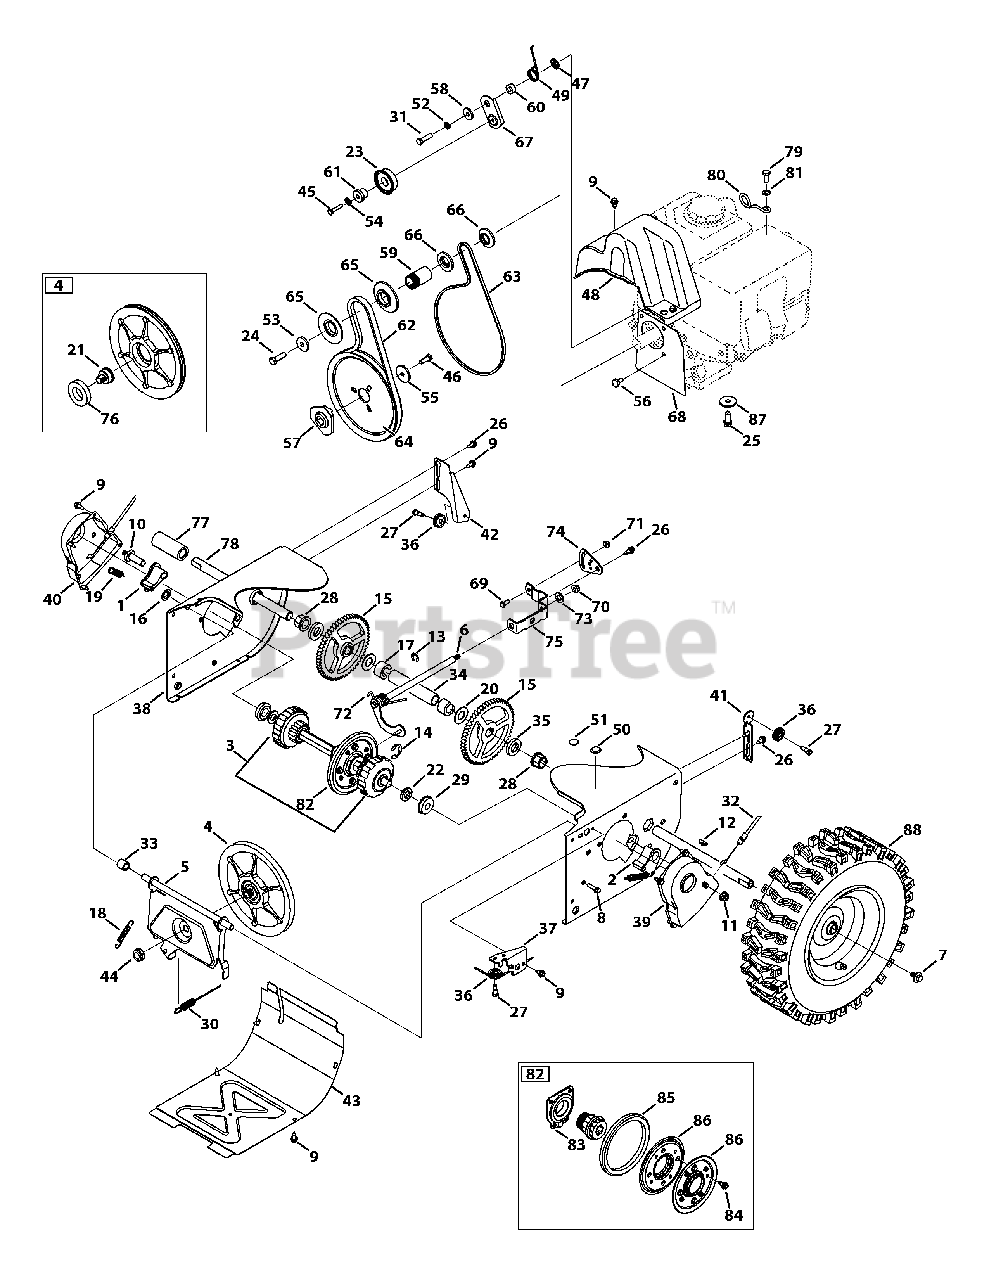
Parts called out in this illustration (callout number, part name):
1	Dogg Assembly, RH
2	Dogg Assembly, LH
3	Drive Shaft Assembly (w/.8125 diam hex shaft)
3	Drive Shaft Assembly (w/.75 diam hex shaft)
4	Friction Wheel Disc Assembly
5	Friction Wheel Support
6	Rod Shift Assembly
7	Screw, 5/16-24 x .750
8	Screw, 1/4-20 x 1.000
9	Screw, 1/4-20 x .625
10	Actuator Shaft
11	Nut, Flangelock, 3/8-16
12	Hi-Pro Key, 3/16 x 3/4 DIA
13	E-Ring
14	Retainer Ring
15	Gear, 56T
16	Nut, Speed, .500
17	Spacer, .76 x .75
18	Extension Spring, .380 x 2.500
19	Extension Spring, .500 x 1.71
20	Washer, Flat, .76 x 1.49
21	Friction Pin, Disc Bearing
22	Spacer .68 ID x 1.25 OD x .20
23	Pulley Assembly
24	Hex Head Screw, 3/8-24 x 1.25
25	Taptite Sems Screw, 3/8-16 x 1.000
26	Screw, Shoulder, .368 x .113 x 1/4-20
27	C Screw, Shoulder, .340 x .335 x 1/4-28
28	Hex Flange Bearing, .75 ID
29	Ball Bearing 17 x 40 x 12
29	Ball Bearing .5625 x 1.375 x .4375
30	Drive Clutch Cable
31	Hex Head Screw, 5/16-24 x 1.25
32	Steering Cable
33	Spacer, .508 x .75
34	Axle Support Tube
35	Spacer, Axle
36	Roller Cable
37	Auger Cable Guide Bracket
38	Wheel Drive Frame
39	Shaft Retainer, LH (w/.8125 diam hex shaft)
39	Shaft Retainer, LH( w/.75 diam hex shaft)
40	Shaft Retainer, RH (w/.8125 diam hex shaft)
40	Shaft Retainer, RH( w/.75 diam hex shaft)
41	Auger Clutch Cable Guide Bracket
42	Drive Clutch Cable Guide Bracket
43	Frame Cover
44	Nut, Flange, 5/8-18
45	Taptite Screw, 1/4-20 x 1.250
46	Hex Head Screw, 5/16-24 x .875
47	Nut, Push-On, .25 DIA
48	Belt Cover
49	Spring, Torsion, .850 x .333
50	Plug, 3/8 ID
51	Plug, 1/2 ID
52	Washer, Lock, 5/16
53	Washer, Flat, .45 x 1.5
54	Washer, Lock, 1/4
55	Washer, Flat, .34 x 1.50
56	Screw, Shoulder
57	Pulley Adapter, .75 DIA
58	Spacer, Shoulder, .3175 x .500
59	Spacer, .875 x 1.185
60	Spacer, .340 x .750
61	Spacer, Shoulder, .260 x .785
62	Belt, .500 x 37.00
63	V Belt, 3/8 x 35.68"
64	Auger Pulley, 8.1 x .5
65	Pulley, Half, 4L-V x 2.600
66	Pulley, Half, 3/8-V x 1.7160
67	Drive Idler Bracket
68	Cover Plate
69	Hex Head Screw, 1/4-20 x .620
70	Nut, Flangelock, 5/16-18
71	Nut, Flangelock, 1/4-20
72	Spring, Torsion, .750 x .968
73	Washer, Flat, .469 x .875 x .105
74	Speed Selector Pivot Bracket
75	Speed Selector Shift Bracket
76	Ball Bearing, 30 x 55 x 13
77	Spacer, 1.25 x .75 x 3.00
78	Axle, .75 x 11.12
79	Hex Head Screw, 1.25 x 20
80	Cable Guide
81	Washer, Flat, .330 x .630
82	Friction Wheel Assembly
83	Bearing Assembly, Friction Wheel
84	Screw, 5/16-18 x .750
85	Friction Wheel, 5.5 OD
86	Friction Wheel Plate
87	Washer, Flat, .38 x 1.38
88	Wheel, LH, 16 x 6.5-8
88	Wheel, RH, 16 x 6.5-8
